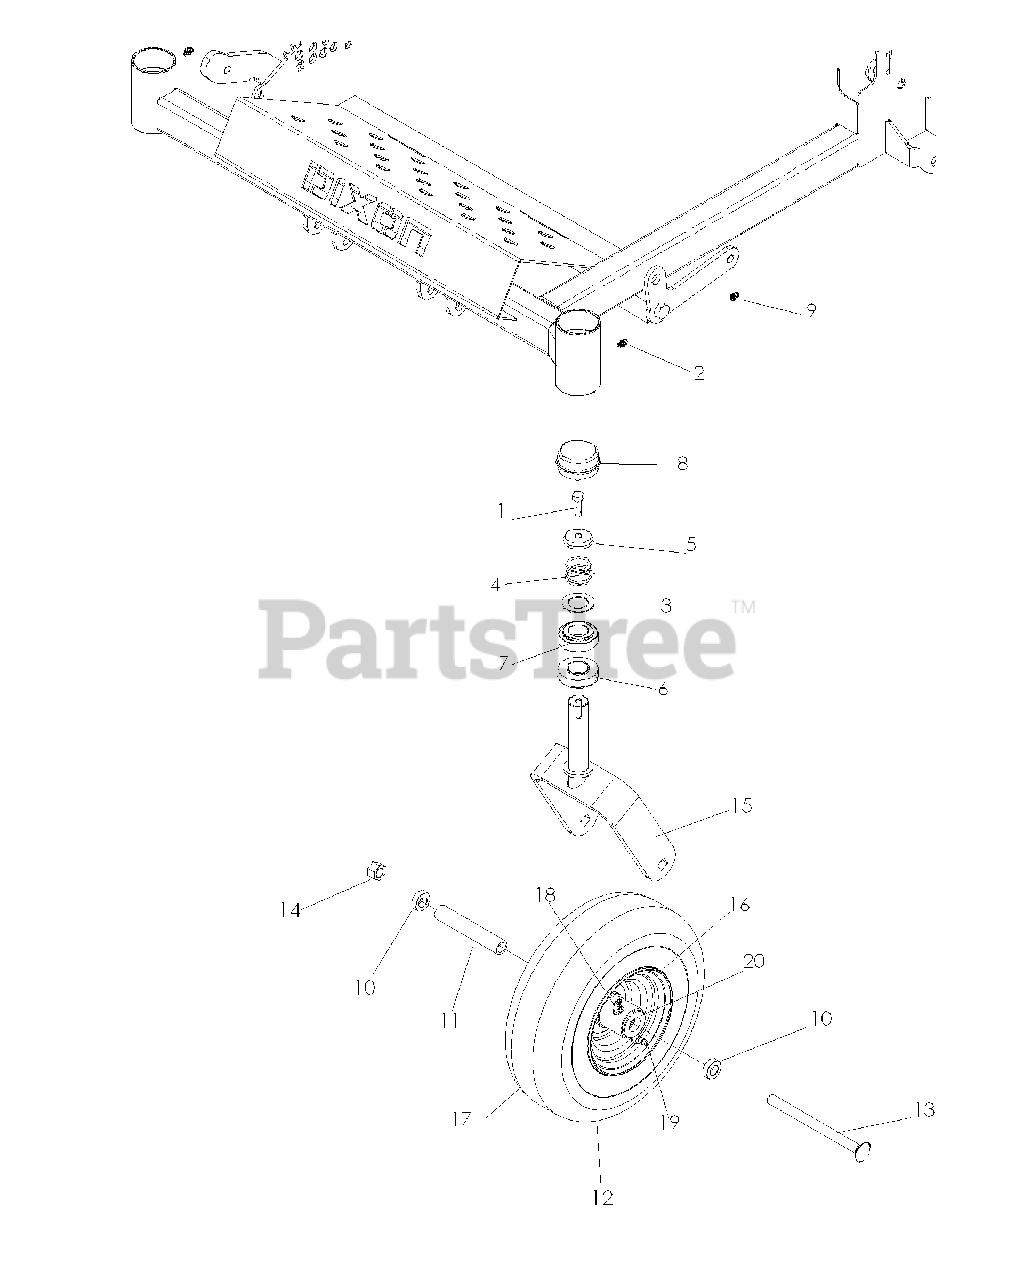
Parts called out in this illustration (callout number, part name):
1	5/16-18X1 HHB G5W/NY
2	ZERK, 3/16, DRIVE IN
3	WASHER, 1.025 ID X 1.64
4	SPRING, CASTER
5	CASTER.PLUG
6	BEARING
7	BUSHING, CASTER
8	GREASE CAP
9	GREASE ZERK-1/4"
10	SPACER, 5/16"
12	TIRE ASSEMBLY, BRG
13	RHSNB 1/2-13 X 6.50 GR2 ZD
14	NUT 1/2-13 HEX NYLOC ZD
15	CASTER DK BLUE
17	TIRE.11"X4"-5.4PLY.SMOOTH.KEND
18	ZERK
19	VALVE STEM TR-412
20	BEARING RETAINER
